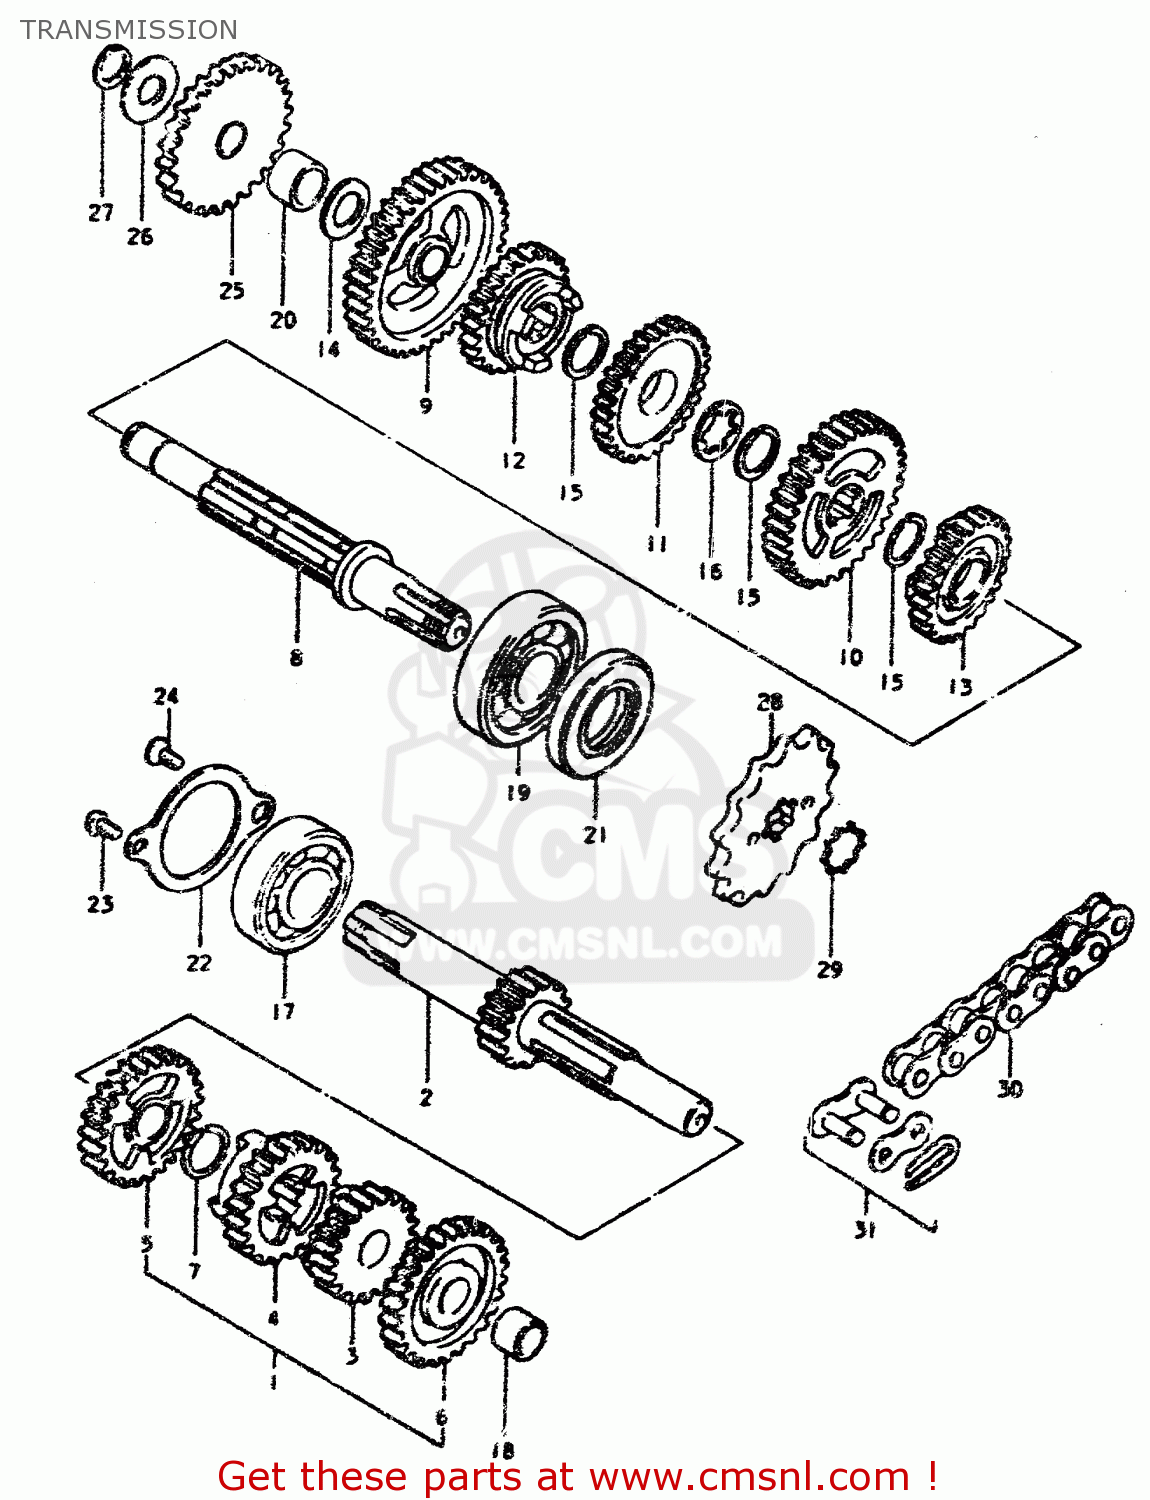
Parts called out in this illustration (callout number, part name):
1	SHAFT,COUNTER
2	SHAFT,COUNTER(NT:12)
3	GEAR,SECOND DRIVE
4	GEAR,THIRD DRIVE
5	GEAR,4TH DRIVE(NT:24)
6	GEAR,FIFTH DRIVE
7	CIRCLIP
8	DRIVESHAFT
9	GEAR,FIRST DRIVEN
10	GEAR,2ND DRIVEN(NT:33)
11	GEAR,3RD DRIVEN(NT:29)
12	GEAR,FOURTH DRIVEN
13	GEAR,5TH DRIVEN(NT:24)
14	WASHER(13X24X1)
15	CIRCLIP
16	WASHER,LOCK
17	BEARING
18	BUSH
19	Bearing
20	BUSH
21	SEAL,OIL(20X40X7)
22	RETAINER,CNTR SHAFT BEARING
23	SCREW
24	SCREW
25	GEAR,KICK STARTER IDLE
26	WASHER
27	CIRCLIP
28	SPROCKET,ENGINE(NT:12)
29	RING,ENGINE SPROCKET
30	CHAIN, DRIVE (420*114L)
31	JOINT ASSEMBLY,CHAIN
